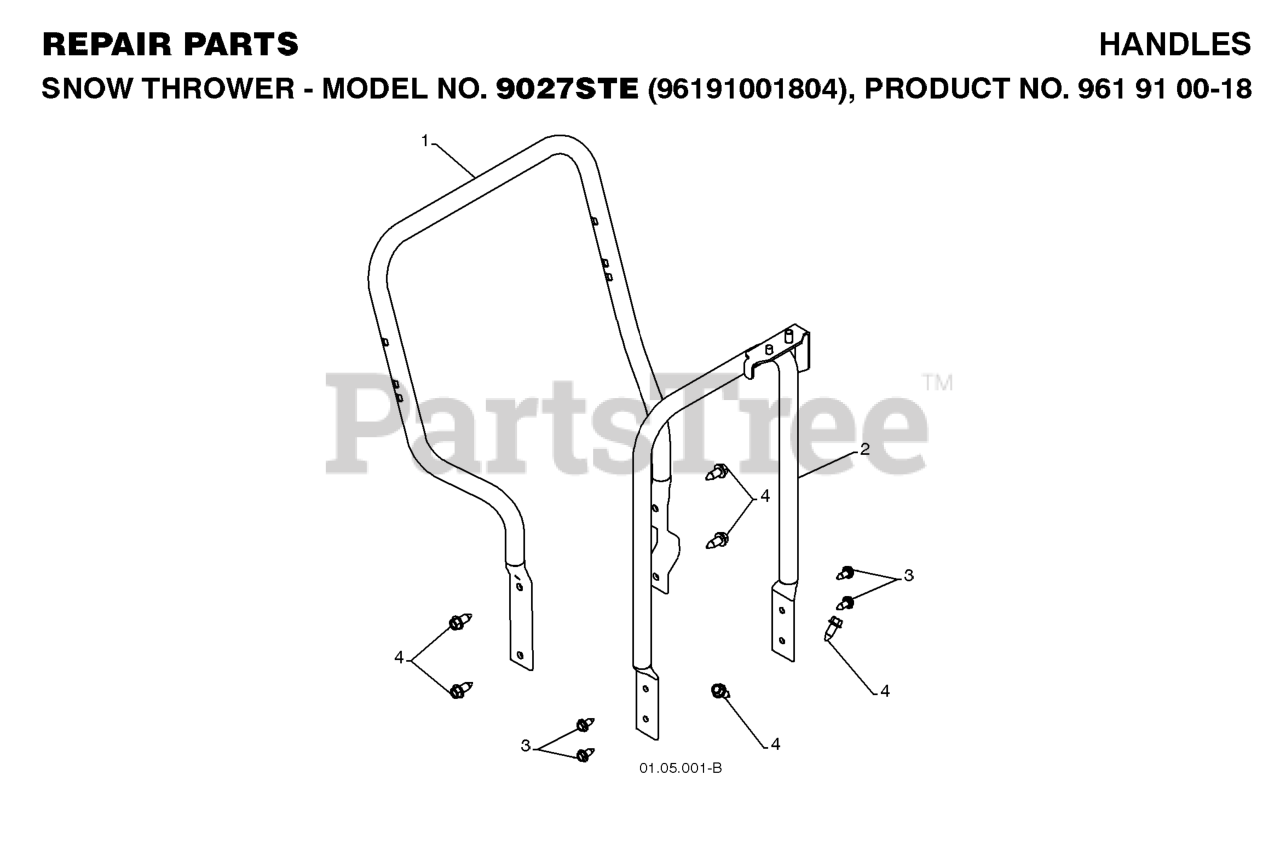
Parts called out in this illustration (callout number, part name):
2	RP PIVOT SUPPORT
3	SELF-TAPPING SCREW 5/16-18X3/4
4	SCREW 3/8-16X1
